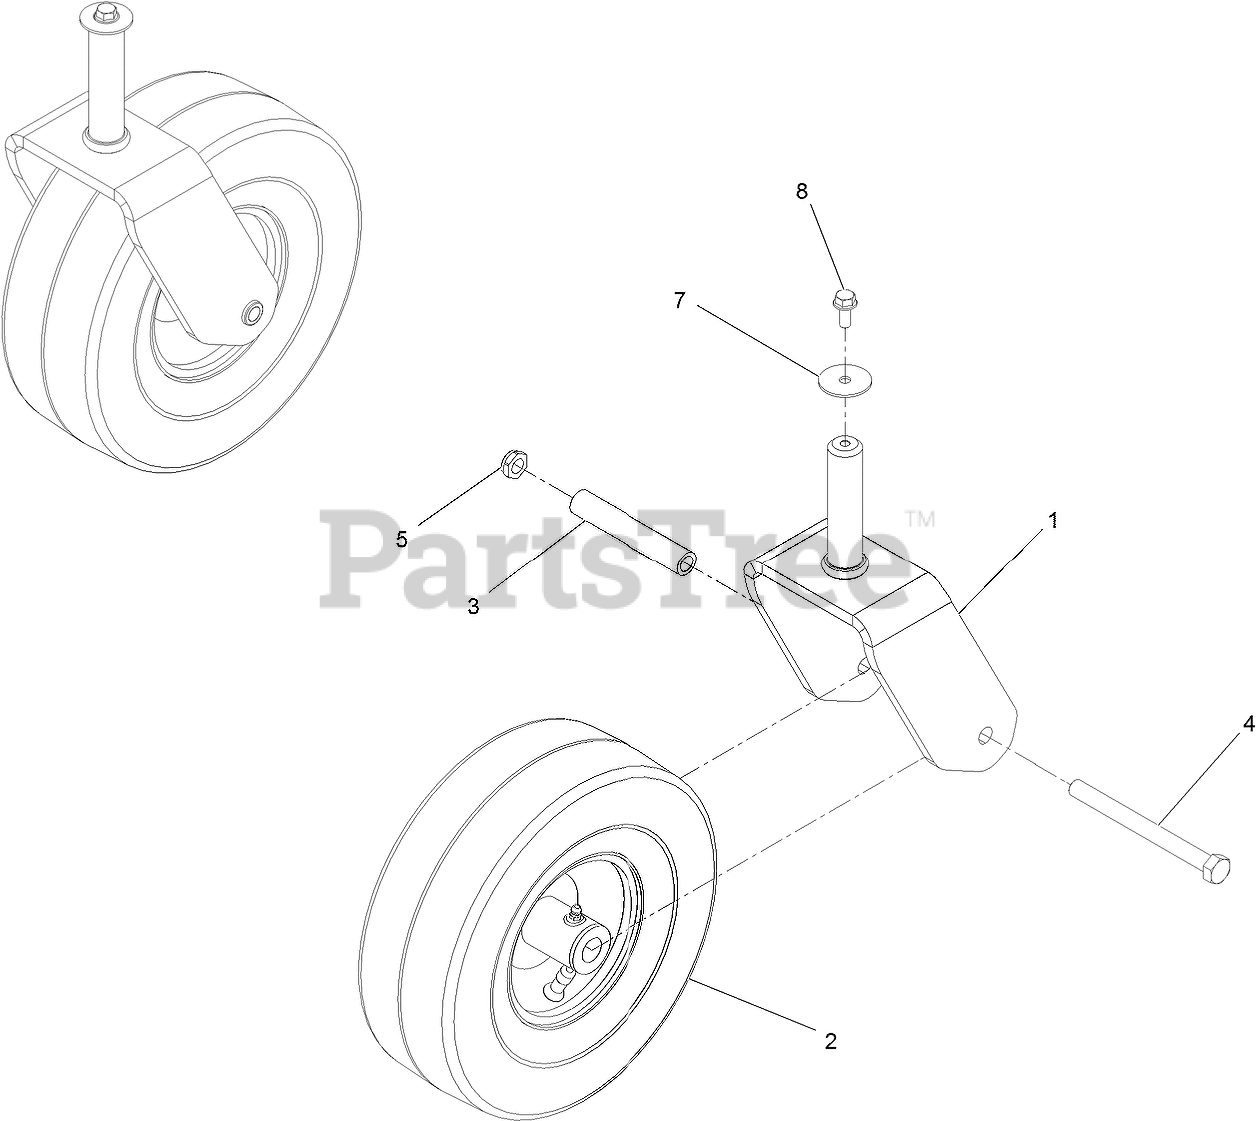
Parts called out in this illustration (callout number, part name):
1	FORK-CASTER
2	TIRE AND WHEEL ASM (C S T)
3	BUSHING-SPANNER
4	SCREW-HH
5	NUT-HEX
7	WASHER-FLAT
8	SCREW-HHF
